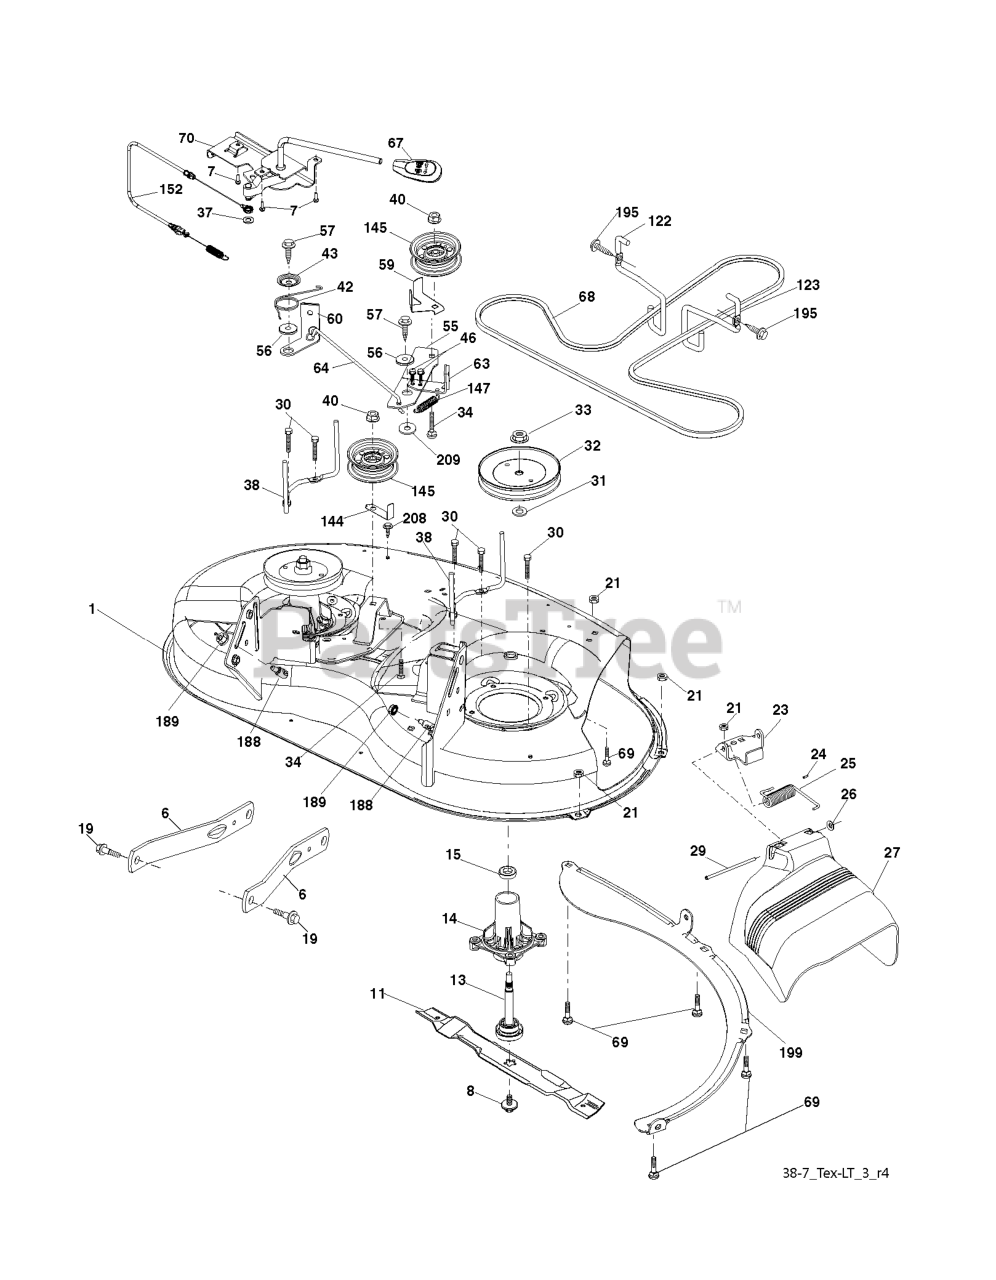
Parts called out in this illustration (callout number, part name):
1	HOUSING
6	ARM.SUSPENSION.MOWER.R
7	SCREW.#10 X 0.750.BOS
8	BOLT.WASHER.ASM.7/16-2
11	BLADE 38" PREMIUM
13	SHAFT.ASM.MDRL.N/GREASE.38
14	RP.HOUSING.MANDREL.4PT.
19	BOLT.SHOULDER
21	LOCKNUT
23	BRKT.DEFLECTOR.38"2005+
24	CAP-SLEEVE LT
25	SPRING.TORSION.DEFLECT
26	NUT PUSH M
27	SHIELD.DEFLECTOR.MWR.38-7/97CM
29	ROD.HINGE
30	SCREW, WASHER HEAD
31	WASHER.SPACER.MANDREL
32	PULLEY.MANDREL.5.0.PD.38"
33	NUT.FLANGE.LOCK.TOP
34	BOLT.3/8-16X1.50
37	WASHER
38	KEEPER BELT LH MANDREL
40	NUT LOCK FLG 3/8-16 UNC
42	SPRING.TORSION.BRAKE
43	SRPING.TORSION.RETAINE
46	SCREW.1/4-20X5/8
56	SPACER.RETAINER
57	SCREW 3/8-16X1
59	GUARD, BELT
60	ARM BRAKE MOWER RH 38"
63	RP ARM.BRAKE.MOWER.38"LH.TEX
64	LINK BRAKE
67	HANDLE.CLUTCH.CABLE.LT
69	BOLT
70	CLUTCH.ASM.MANUAL.LT.PRED
122	KEEPER BELT ENGINE LH
123	KEEPER BELT RH
144	KEEPER BELT
145	PULLEY.IDLER.48"PRIMARY
147	SPRING RETURN
152	CABLE.CLUTCH.MANUAL.
188	STUD.FASTNER.W/ANTI-ROTATE
189	NUT LOCK HEX FLANGE 5/16-18
195	SCREW, 3/8-16X3/4
199	BAFFLE.VORTEX.FRONT.38"
208	SCREW 3/8-16X1/2
209	WASHER 12/32X2X10GA
